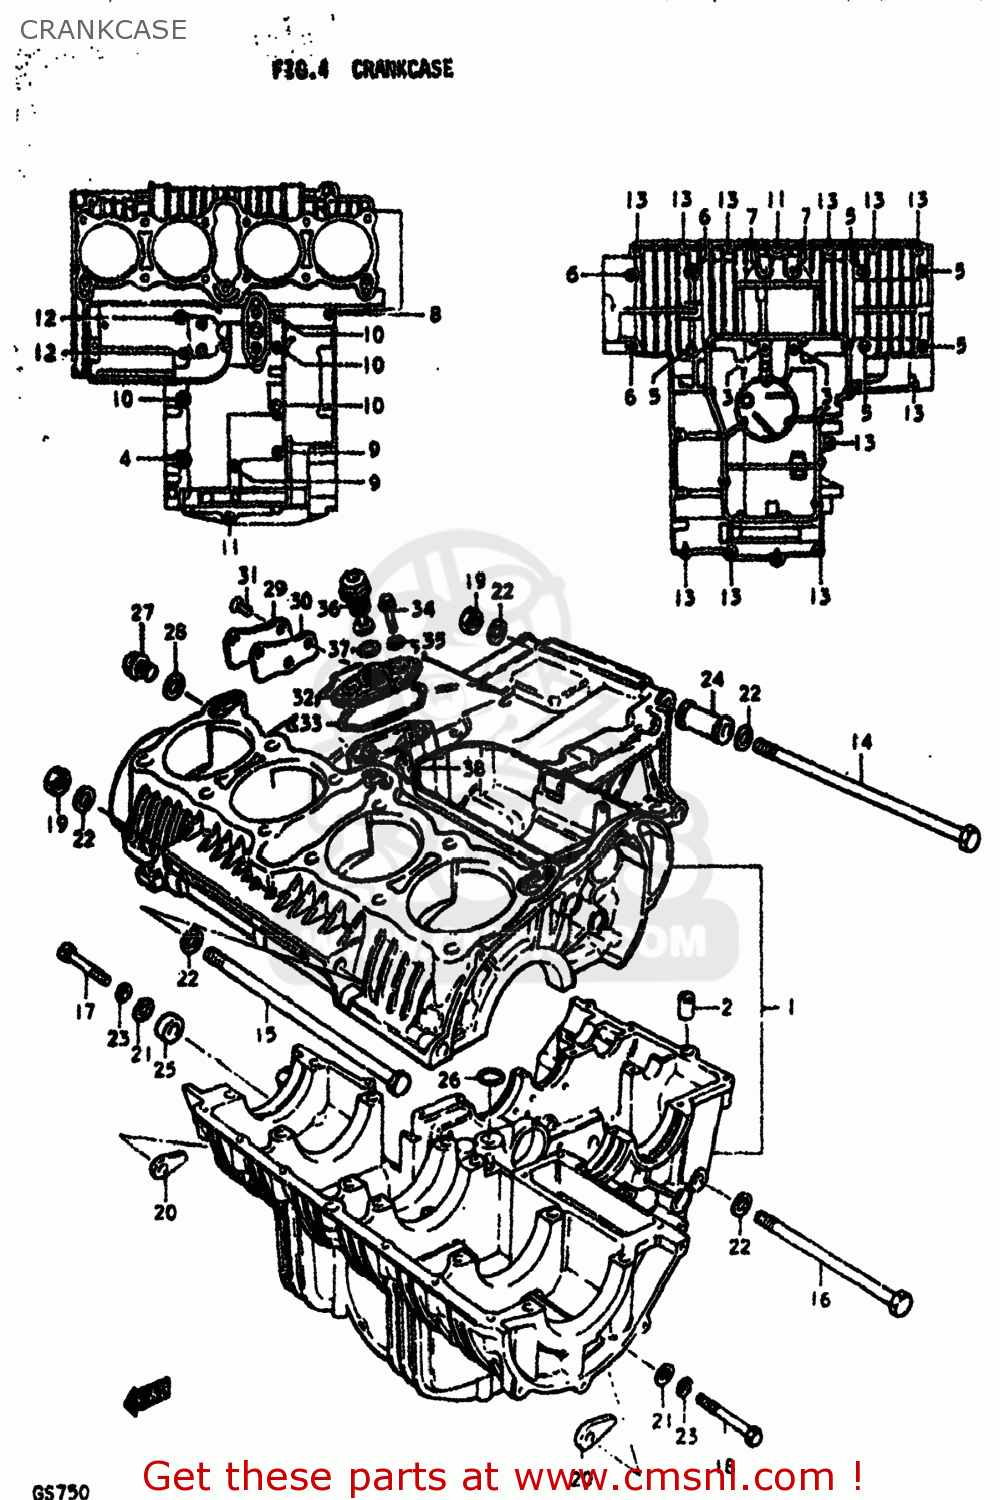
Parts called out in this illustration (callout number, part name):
1	CRANKCASE SET
2	PIN
3	BOLT
4	BOLT (8X95)
5	BOLT 8X90
6	BOLT 8X65
7	BOLT
8	BOLT 6X100
9	BOLT (6X90)
10	BOLT (6X80)
11	BOLT
12	BOLT,UNDER
13	BOLT
14	BOLT 10X250
15	BOLT 10X235
16	BOLT 10X160
17	BOLT 10X65
18	BOLT 10X55
19	NUT
20	NUT
21	WASHER(10.5X20X3.2)
22	WASHER
23	LOCK WASHER
24	SPACER
25	SPACER (10.2X24X11)
26	O RING(D:3.2,ID:12.9)
27	PLUG (14X12)
28	GASKET(14X19.2X2) (NAS)
29	CAP,OIL GALLERY
30	GASKET,OIL GALLERY (MCA)
31	SCREW
32	HOUSING,OIL PRESSURE SWITCH
33	O RING,PRESSURE SWITCH HOUSING
34	BOLT
35	GASKET (NAS)
36	SWITCH ASSEMBLY
37	O RING(D:1.9,ID:18.8)
38	GROMMET,STARTING MOTOR
